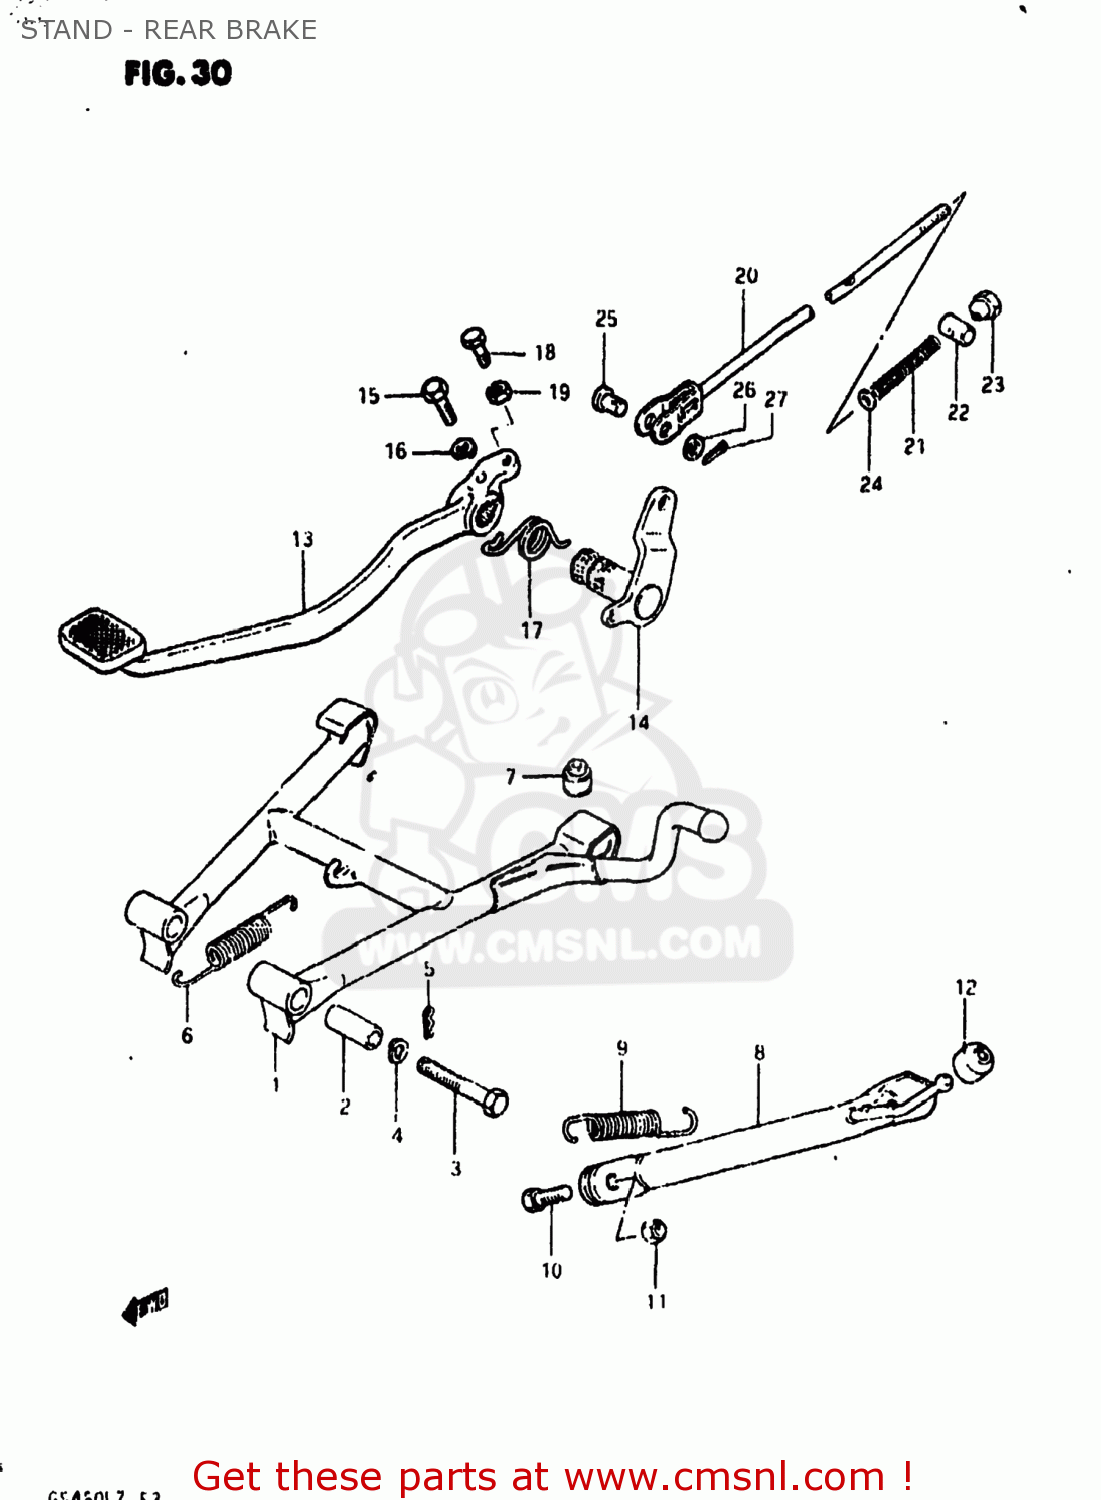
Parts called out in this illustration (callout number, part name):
1	STAND,CENTER
2	SPACER(10X16X38.8)
3	BOLT
4	LOCK WASHER
5	CLIP
6	SPRING
7	CUSHION
8	STAND,SIDE
9	SPRING
10	BOLT(10X30)
11	NUT
12	CUSHION
13	PEDAL,BRAKE
14	ARM,BRAKE PEDAL ROD
15	BOLT
16	LOCK WASHER
17	SPRING
18	BOLT
19	NUT
20	ROD ASSEMBLY,REAR BRAKE
21	SPRING
22	PIN
23	NUT
24	WASHER
25	PIN(L:13.5)
26	WASHER
27	PIN 20X20
